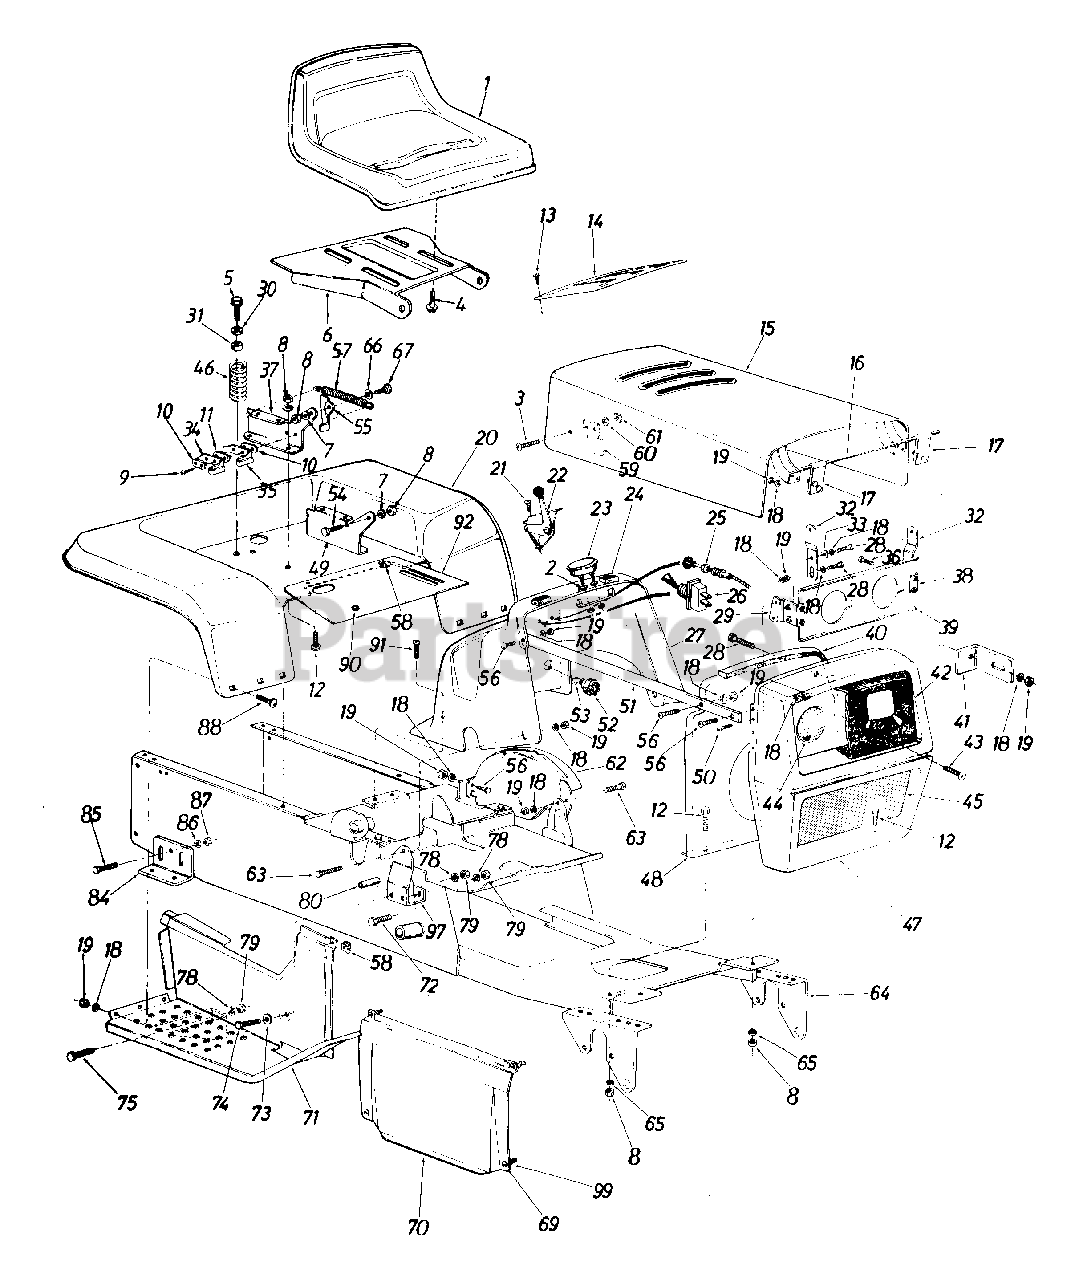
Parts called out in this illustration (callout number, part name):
1	Seat Ass'y.
2	L-Wash. .190" I.D.
3	Truss Hd. Mach. Scr. #10-24 x .38" Lg.
4	Hex Wash. Hd. Self-Tap Scr. 3/8-16 x .75" Lg.
5	Hex Wash. Hd. Tap Scr. 5/16-18 x .75" Lg.
6	Seat Pivot Bracket
7	L-Wash. 5/16" I.D.
8	Hex Nut 5/16-18 Thd.
9	Hex Wash. Hd. AB-Tap Scr. #8 x .5" Lg.
10	Insulator Plate
11	Insulator Boss Plate
12	Hex Bolt 5/16-18 x .75" Lg.
13	Self-Tap Oval Hd. Scr. 1/2" Lg.
14	Dash Panel Cover
15	Hood Ass'y.
17	Hood Hinge Ass'y.
18	L-Wash. 1/4" I.D.
19	Hex Nut 1/4-20 Thd.
20	Rear Fender
21	Fl-Hd. Truss Scr. #10 x .62" Lg.
22	Throttle Control
23	Ammeter
24	Rubber Bumper
25	Choke Control
26	Light Switch
28	Hex Bolt 1/4-20 x .62" Lg.
29	Hood Support Brkt. Ass'y. - R.H.
30	Fl-Wash. .344" I.D. x .875"
34	Safety Switch (Seat)
35	Safety Switch (Seat)
36	Hex Bolt 1/4-20 x .38" Lg.
38	Hood Support Brkt. Ass'y. - L.H.
41	Heat Shield Brkt.
42	Head Lamp Bezel
43	Truss Mach. Scr. #10-24 x .50" Lg.
44	Head Lamp
45	Grille Screen
46	Compression Spring 4.5" Lg.
50	Truss Mach. Scr. 1/4-20 x .75" Lg.
51	Grille Strap
52	Ignition Switch
53	Ignition Key
54	Shld. Bolt .437" Dia. x .162"
55	Seat Lift Bracket
56	Hex Bolt 1/4-20 x .75" Lg.
57	Extension Spring 5.31" Lg.
58	Clip-On Receptacle
61	Hex Nut #10-24 Thd.
62	Speed Control Guide
63	Truss Mach. Scr. 1/4-20 x .75" Lg
64	Frame Ass'y.
65	Bell-Wash. 5/16" I.D.
66	Spr. Wash. .445" I.D. x .75"
67	Shld. Bolt .437" Dia. x .268"
69	1/4-Turn Stud
70	Hood Lower Side Panel
71	Foot Step Panel Ass'y. - R.H.
72	Hex Bolt 3/8-16 x 1.00" Lg. Grade 5
73	Fl-Wash. .385" I.D. x .62" O.D.
74	Hex Bolt 3/8-16 x 3.00" Lg.
75	Hex Bolt 3/8-16 x 1.00" Lg. Grade 5
78	L-Wash. 3/8" I.D.
79	Hex Nut 3/8-16 Thd.
80	Spacer .375" I.D. x .62" O.D. x 2.00" Lg.
84	Transaxle Support Brkt.
85	Rd. Hd. Rib Neck Scr. 3/8-24
86	L-Wash. 3/8" I.D.
87	Hex Nut 3/8-24 Thd.
88	Carr. Bolt 1/4-20 x .50" Lg.
90	Snap Bushing
91	Fl-Hd. Self-Tap Scr. 1/4-20 x 62" Lg
